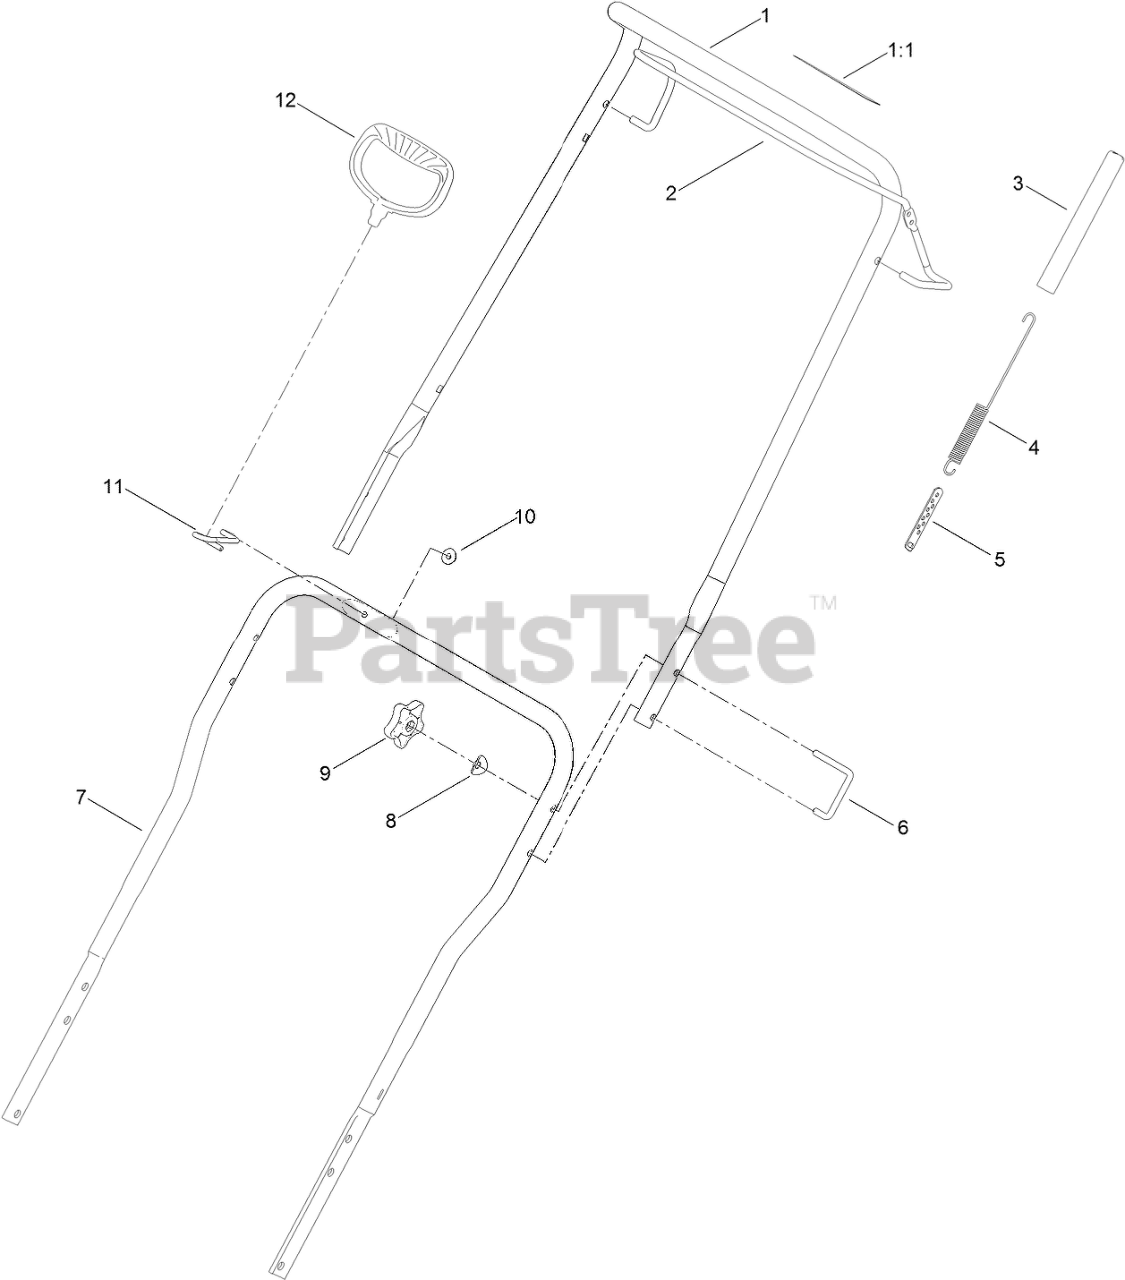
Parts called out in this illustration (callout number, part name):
1	UPPER HANDLE ASM
1:1	DECAL-DRIVE, ROTOR
2	BAIL-CONTROL
3	COVER-SPRING
4	SPRING-EXTENSION, CLUTCH
5	ADJUSTER-CABLE, CLUTCH
6	LOCK-HANDLE
7	HANDLE-LOWER
8	WASHER
9	KNOB-HANDLE
10	NUT-HEX FLG
11	GUIDE-ROPE
12	HANDLE-RECOIL
